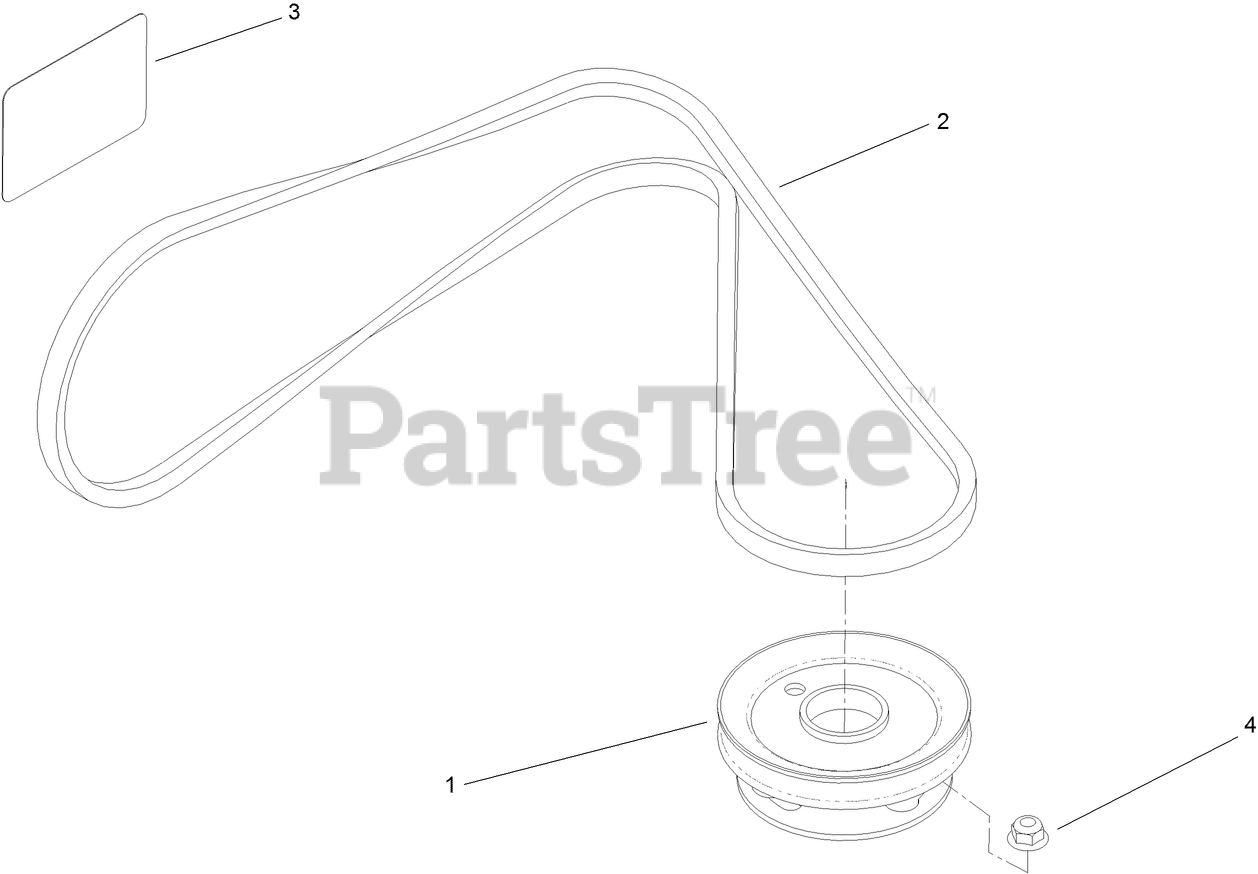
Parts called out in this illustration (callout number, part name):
2	BELT-V
3	DECAL-ROUTING, BELT
4	NUT-HF, NI
